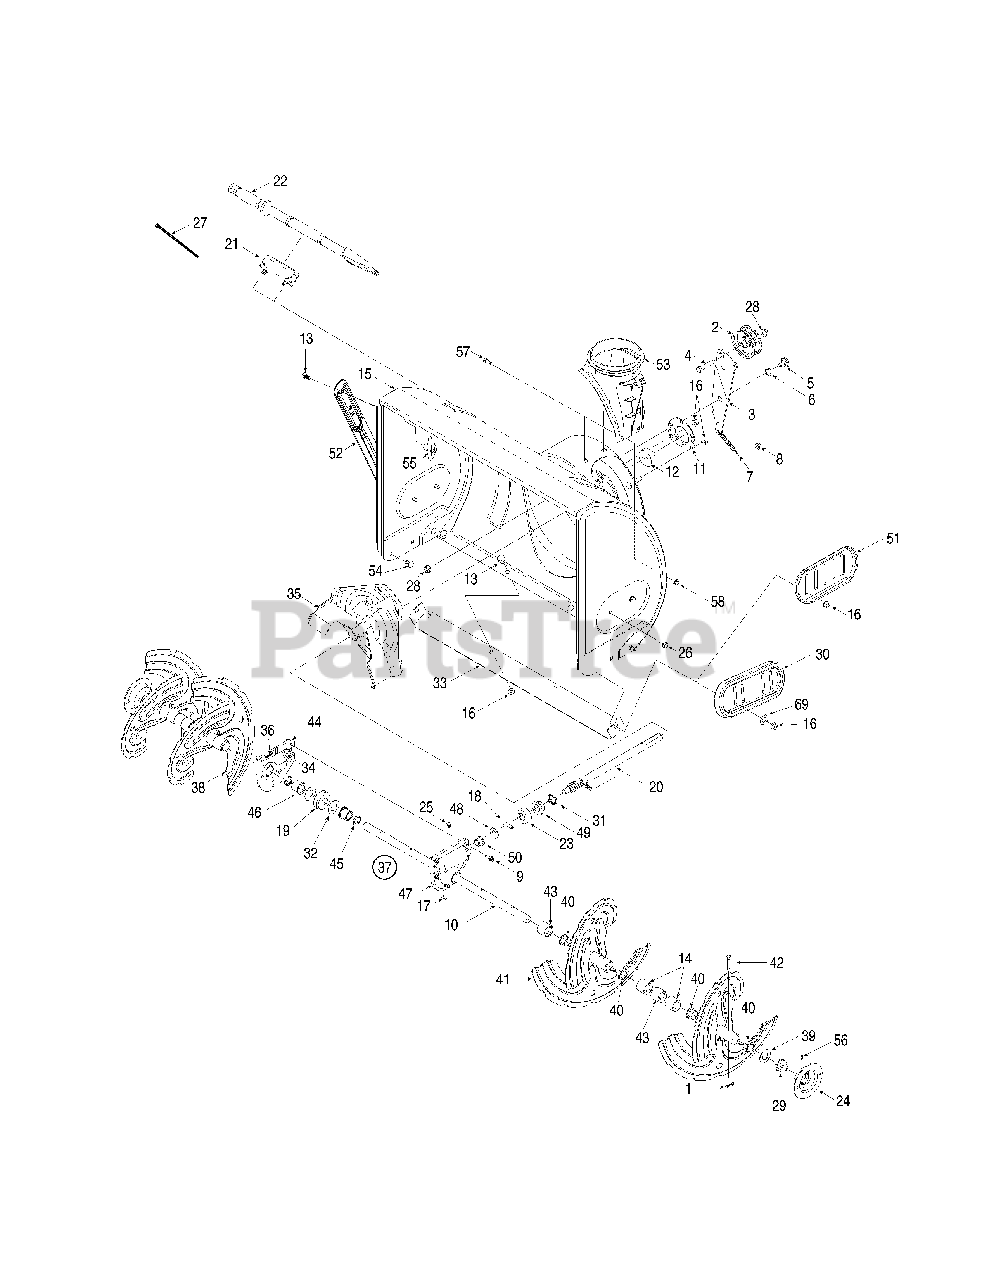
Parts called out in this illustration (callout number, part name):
1	Bow-Tie Cotter Pin
2	Flat Idler Pulley
3	Auger Idler Bracket
4	Hex Screw 3/8-16 x 1.75
5	Shoulder Screw .625 Dia. x .170
6	Wave Washer .660 ID x .88 OD x .010
7	Extension Spring
8	Hex Patch L-Nut 5/16-18
9	Thd Form ing Screw. 1/4-20 x .75 Lg.
10	Auger Axle
11	Bearing Plate
12	Self-align ing Bearing
13	Carriage Bolt 5/16-18 x .75
15	Auger Housing Ass'y 30"
16	Flange Locknut 5/16-18 Gr. F, Nylon
17	Wood ruff Key 3/16 x 5/8 HT
19	Worm Gear
20	Impeller Shaft
21	Mounting Bracket
22	Chute Clean-Out Tool
23	Thrust Collar
24	Bearing Housing
26	Hex TT Screw 5/16-18 x .75
27	Cable Tie
28	Flange Lock-Nut 3/8-16 Gr. F Nylon
29	Hex. Flange Bearing.751" ID
30	Slide Shoe - Polymer
30	Deluxe Polymer Reversible Shoe Kit
32	Flat Washer .76 ID x 1.5 OD x .03
33	Shave Plate
34	Alvania Grease
35	Impeller Ass’y
36	Three Bond Seal ant 1217H
37	Gear Assembly Complete, 30"
38	Spiral Assembly RH
39	Flat Washer .760 ID x 1.49 OD
40	Flange Bearing
41	Spiral Assembly LH
42	Shear Pin .25 x 1.50 Gr. 2
44	Reducer Housing RH Ass'y
45	Oil Seal 3/4 ID
46	Flange Bearing
47	Reducer Housing LH Ass'y
48	Fl. Washer .510 x 1.120 x .060
49	Flange Bearing
50	Flange Bearing
51	Slide Shoe - Steel
53	Chute Adapter
54	Carriage Bolt 5/16-18 x 1.00" Lg (w/plastic slide shoe)
54	Carriage Bolt 5/16-18 x .75 (w/steel slide shoe)
56	Grease fitting
57	Carriage Screw 1/4-20 x .75 Gr. 5
58	Hex L-Flanged Nut 1/4-20 Gr. F Nylon
